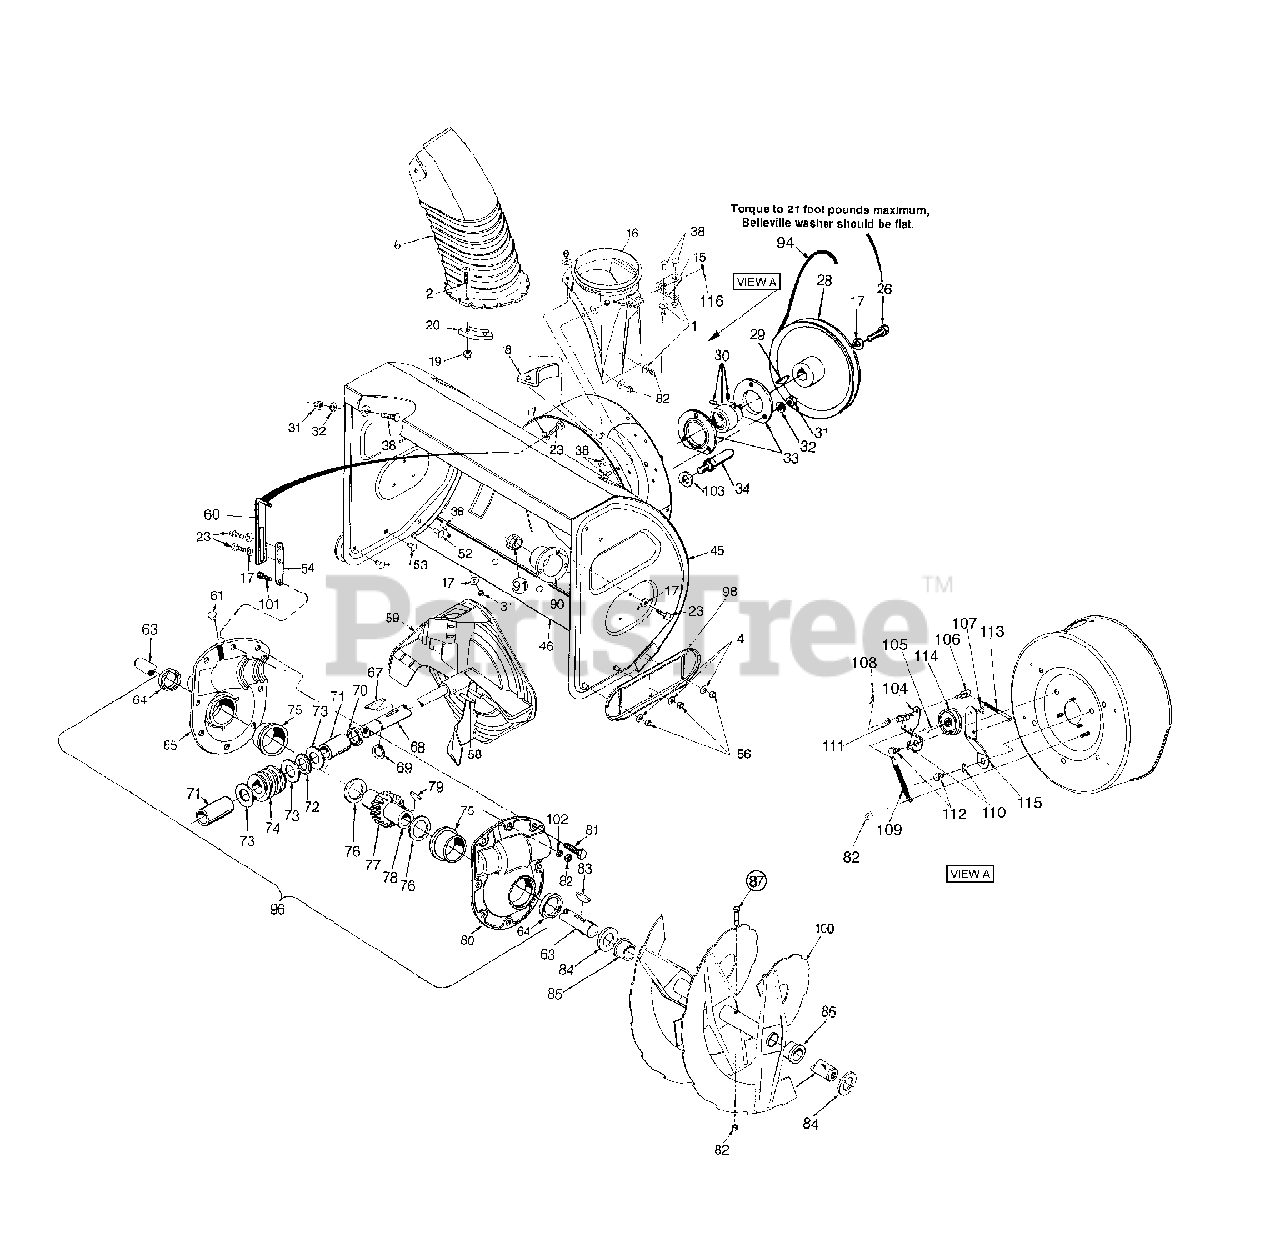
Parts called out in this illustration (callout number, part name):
1	Flat Washer .344 ID x .875 OD
2	Truss. Hd. Mach. Scr. 1/4-20 x .75
4	Belleville washer
6	6" Lower Chute Remote Tilt
16	Chute Adapter
17	Bell. Washer .345 ID x .88 OD x .06
19	Hex Cent. L-Nut 1/4-20 w/ Flange
20	Chute Flange Keeper
23	Hex Wash HD Self-Tap Scr 5/16-18 x .75
26	Hex Screw 5/16-18 x .75
28	1/2" V-Pulley .875 ID x 10.12 OD
29	#9 Hi-Pro Key 3/16 x 3/4 Dia HT
30	Self-Aligning Bearing .875 ID
31	Hex Nut 5/16-18 GD. 5
32	L-Wash 5/16 ID
33	Bearing Housing
34	Belt Keeper Studs 3/8-16 x 2.75
38	Carriage Bolt 5/16-18 x .75
52	Carriage Bolt 3/8-16 x 1.00 Gr. 5
53	Carriage Bolt 3/8-16 x .75" Lg.
56	Hex Jam Nut 3/8-16
58	Spring Spiral Pin Heavy 5/16 dia x 1.7
61	Barbed Plug
63	Spiral Axle -33"
64	Oil Seal 1.50 ID Garlock (76 x 6223)
65	Gear Housing Half - RH
67	#9 Hi-Pro Key 3/16 x 3/4 dia HT
68	Auger Control Shaft
69	Snap Ring for .875 dia. shaft
70	Oil Seal for .875 ID (76 x 6133)
71	Sleeve Bearing .875 ID
72	Thrust Bearing .88 ID x 1.44 OD x .078
73	Flat Washer .88 ID x 1.4 OD x .125
74	Worm Gear LH Double Thread
75	Flange Brg. 1.5 ID x 1.75 OD x .80
76	Flat Washer 1.5 ID x 2.0 OD x .03
77	Worm Gear LH Double Thread (Bronze)
78	Worm Gear Shaft
79	#91 Woodruff Key 1/4 x 3/4 dia
80	Gear Housing Half LH
81	Hex Flange Scr. 5/16-18 x .75
82	Hex Ins. L-Nut 5/16-18
83	#91 Woodruff Key 1/4 x 3/4 dia
84	Flat Washer
85	Flange Bearing
87	Shear Bolt 5/16-18 x 1.75
91	Flange Bearing w/flats
94	V-Belt 1/2 x 44 LG
96	Worm Gear Box Ass'y
102	5/16 Sprg Wash
103	3/8 Sprg Lock Wash
104	Brkt Ass'y Brkt
105	Scr Hex Cap 3/8-24 x 1.5 GRD 5
106	Adjustment Ferrule
107	Hex Ins L-Nut 3/8-24
108	Intern Cot-Pin 5/16 dia
109	Spr Extn .470 dia x 4.75 Lg
110	Wave Washer .66 ID x .88 OD
111	Fl-Wash SAE .34 x .68
112	Shld Scr .625 dia x .170 x .062
113	Rod Idler Auger
114	3.0 OD Flat Idler with Flanges
116	Plastic Bushing .380 ID 1
